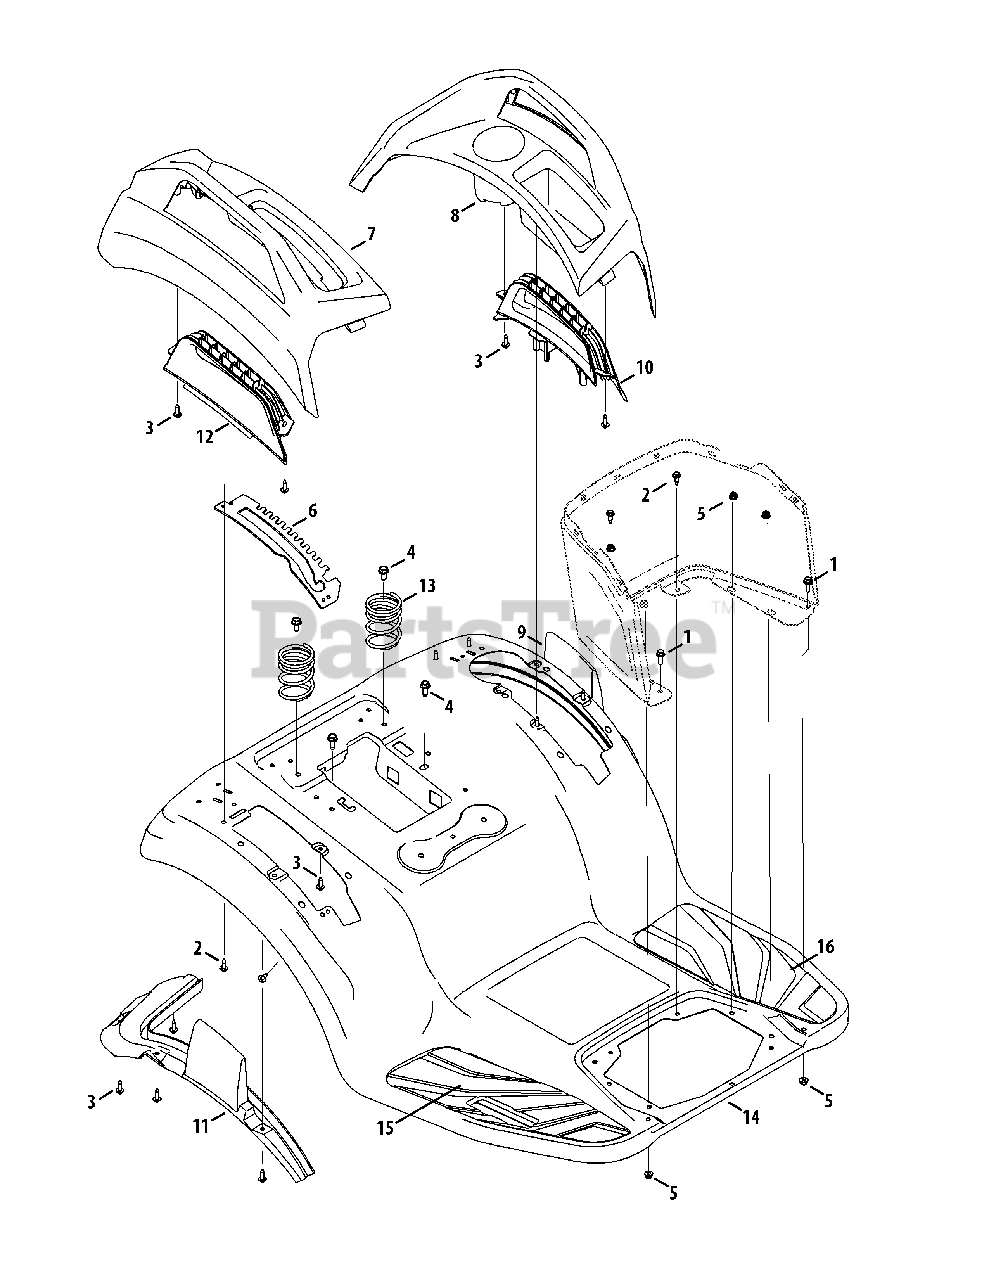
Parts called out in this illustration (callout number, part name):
1	Hex flange Screw, 1/4-20 x .75
2	Screw, M6-1 x .625
3	Screw, 1/4-10 x .75
4	Screw, Self-tapping, 3/8-16, 0.750,
5	Nut, Flange Lock, 1/4-20, Nylon
7	Upper Cover, RH
8	Upper Cover, LH
9	Lower Cover, LH
10	Cover Handle, LH
11	Lower Cover, RH
12	Cover Handle. RH
13	Compression Spring, 2.50 x 3.951 x .207
14	Fender
15	Pad, Foot, RH
16	Pad, Foot, LH
